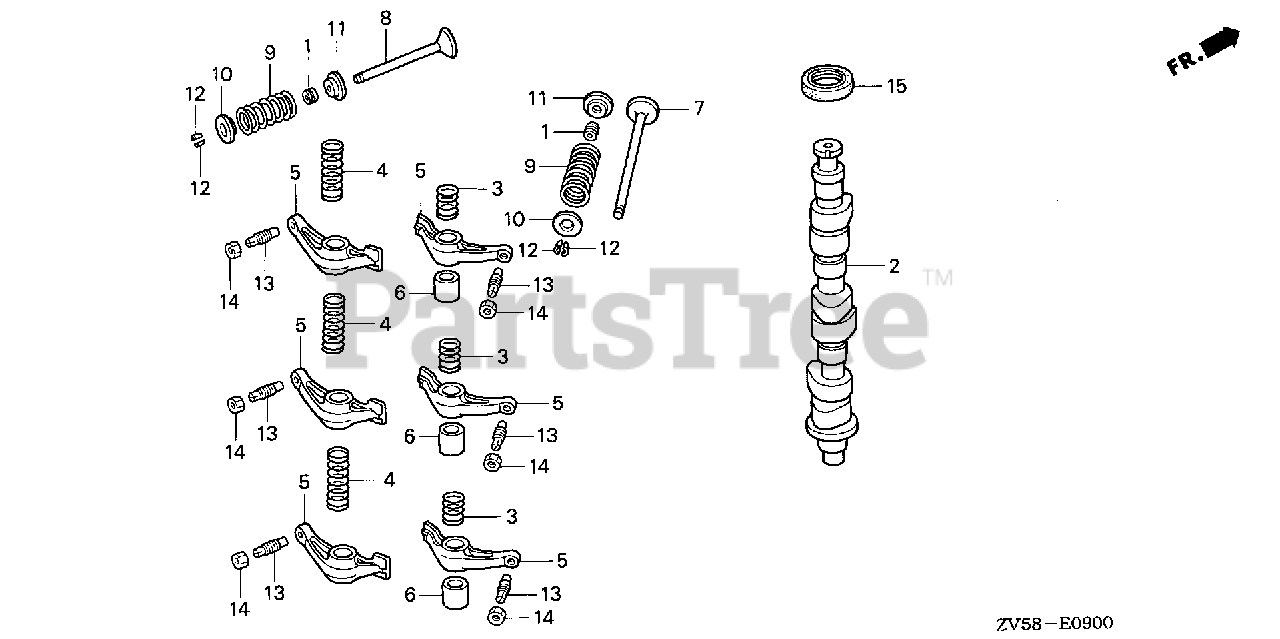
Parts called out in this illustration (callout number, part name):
1	SEAL, VALVE STEM
3	SPRING, ROCKER ARM A
4	SPRING, ROCKER ARM B
5	ARM, IN. ROCKER
6	COLLAR, ROCKER
7	VALVE, IN.
8	VALVE, EX.
9	SPRING, VALVE
10	RETAINER, VALVE SPRING
11	SEAT, VALVE SPRING
12	COTTER, VALVE
13	SCREW, TAPPET ADJUSTING
14	NUT, TAPPET ADJUSTING
15	OIL SEAL (30X42X8)
